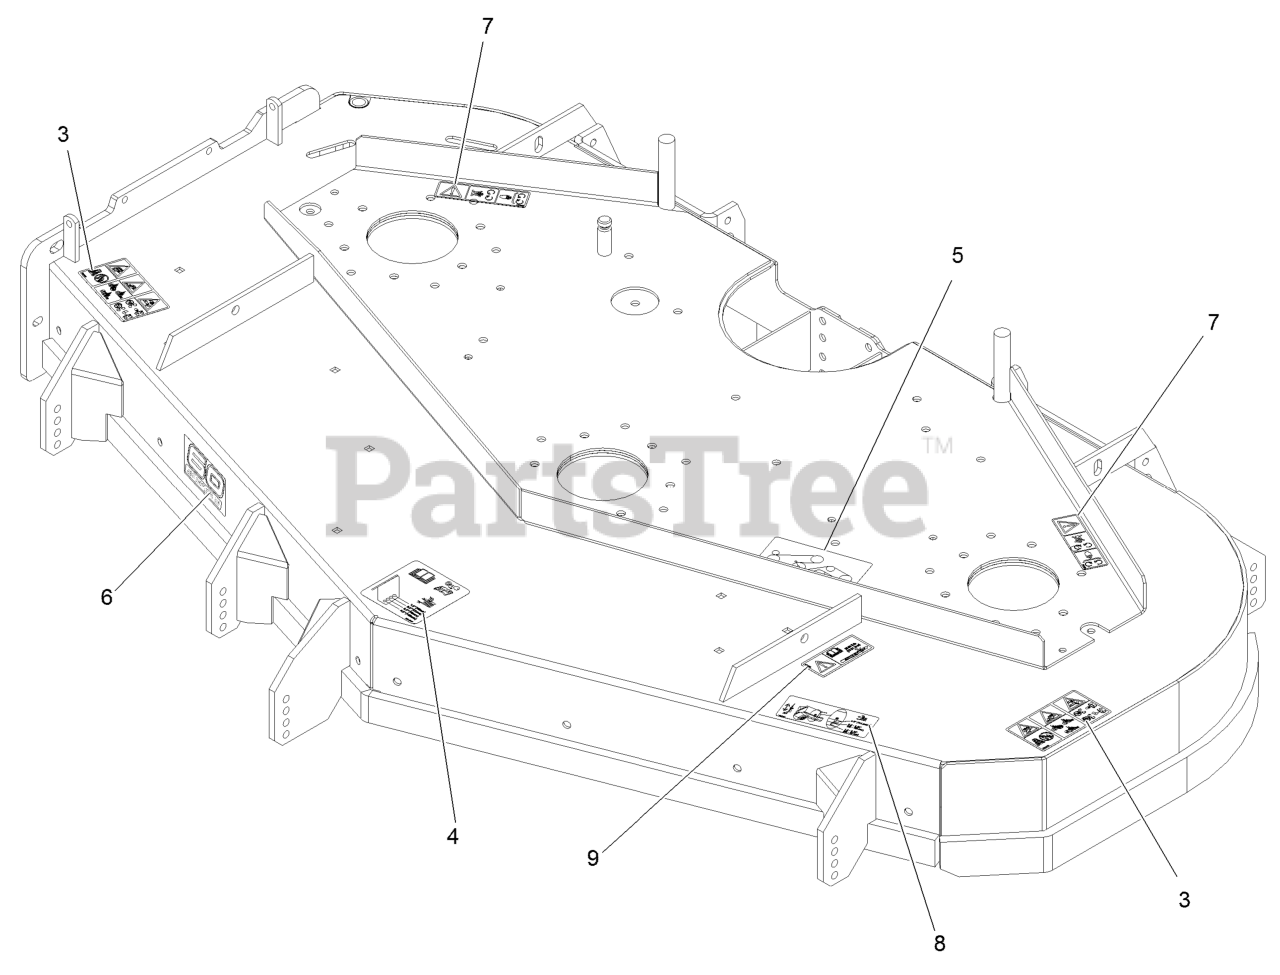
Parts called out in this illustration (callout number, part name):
3	DECAL-DANGER THROWN OBJECTS
4	DECAL-HEIGHT OF CUT
5	DECAL-BELT ROUTING
6	Decal, 605
7	DECAL-COVER, MISSING
8	DECAL-BAFFLE ADJ
9	DECAL-BOLT TORQUE
